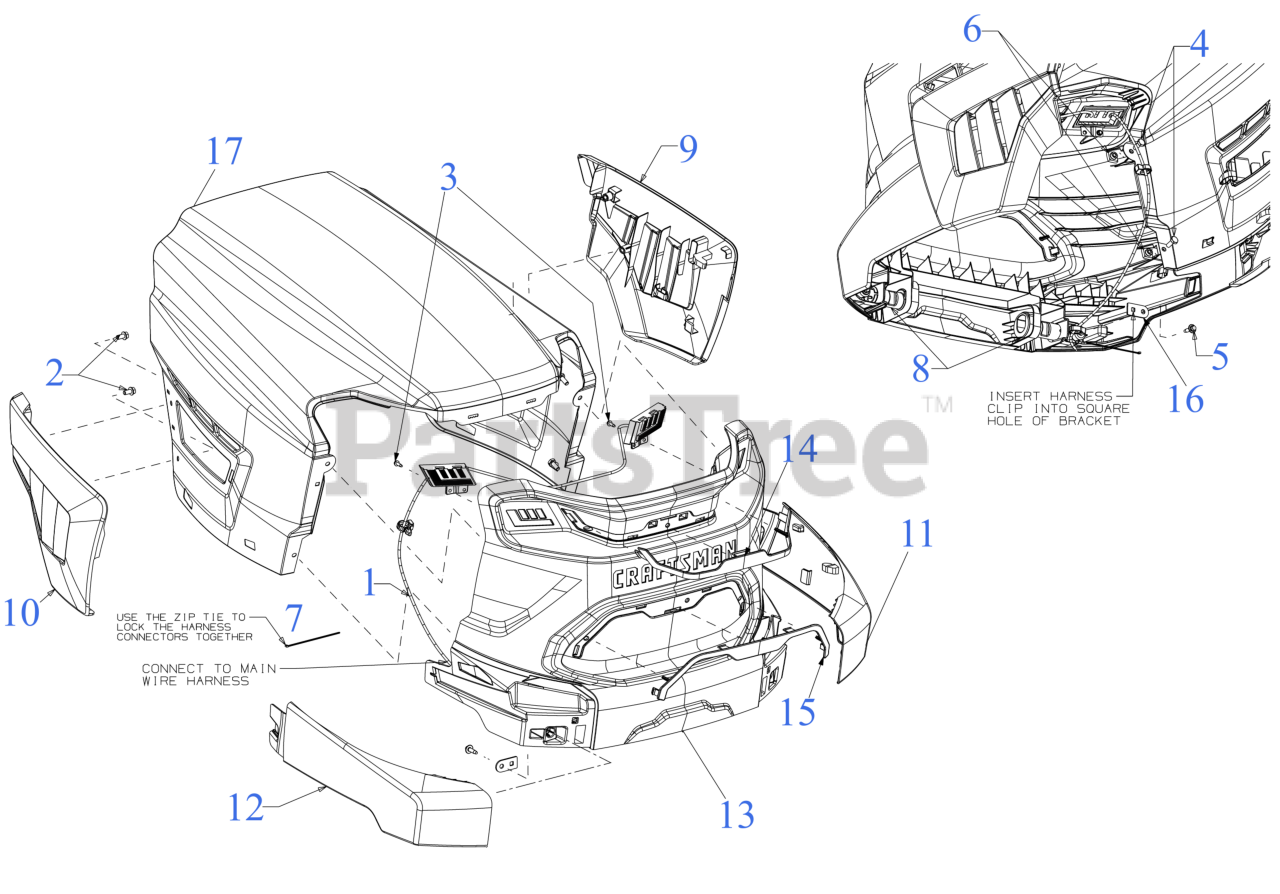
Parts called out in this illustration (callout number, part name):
1	HEADLIGHT HARNESS
2	HEX SCREW 1/4-15 x .50
3	SCREW #8-16 x .50
4	SCREW 1/4-20 x .62 SPEC GR5
5	SCREW 1/4-10 x .750
6	SQUARE NUT 1/4-20
7	CABLE TIE
8	HOOD PIVOT PIN
9	HOOD SIDE COVER (LH)
10	HOOD SIDE COVER (RH)
11	GRILLE PANEL (LH) (LIBERTY RED)
12	GRILLE PANEL (RH) (LIBERTY RED)
13	GRILLE
14	GRILLE TRIM (TOP)
15	GRILLE TRIM (BOTTOM)
16	HARNESS CLIP BRACKET
17	HOOD
